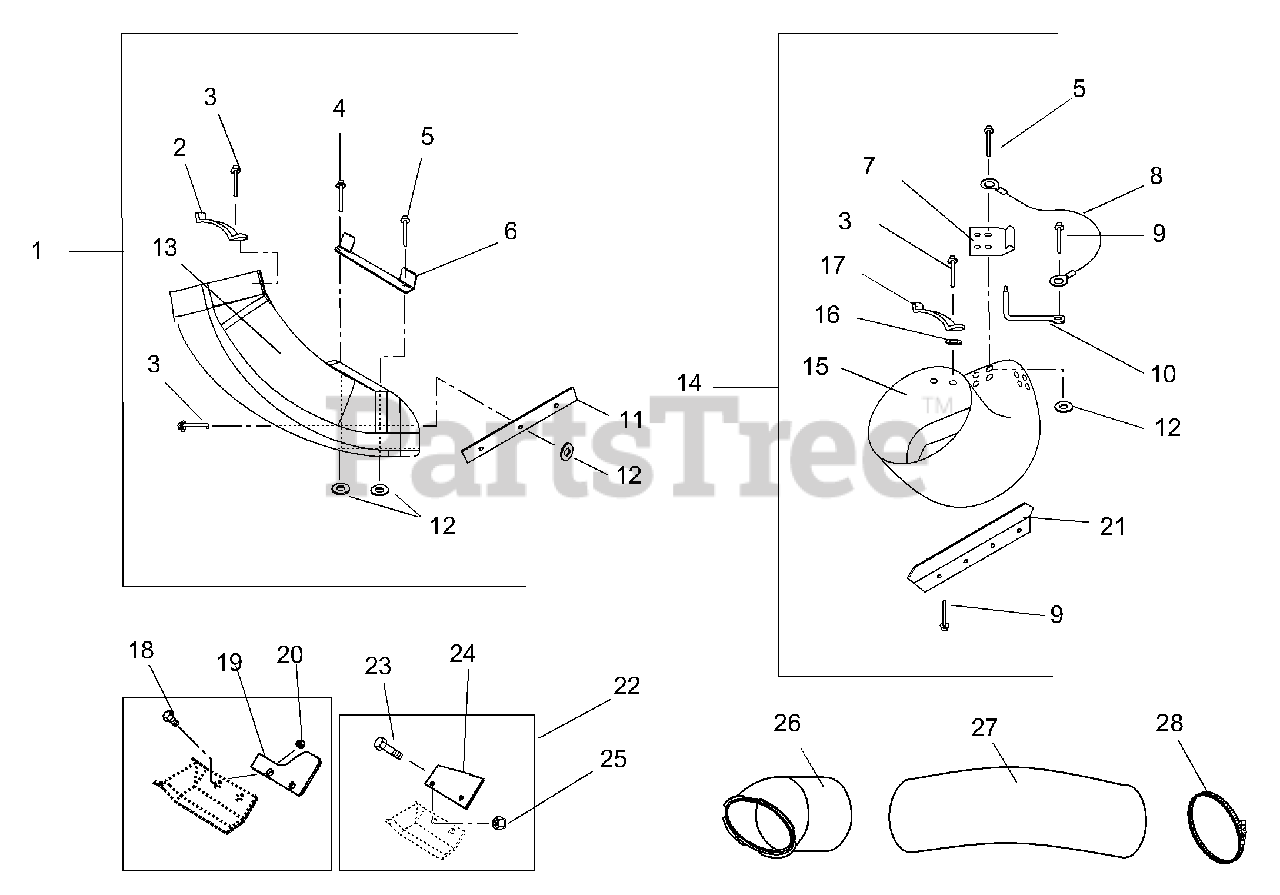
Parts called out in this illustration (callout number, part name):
1	BOOT, 28"&32" DECK BAGGER
2	TUBE RETAINER CLIP
3	RVT-POP.187X.527 DOME ST
4	RVT-POP.187X.277 DOME ST
5	RVT-POP .187X.402 DOME ST
6	BRKT, BAGGER BOOT MOUNT
7	BOOT BRACKET
8	LANYARD
9	RVT-TBLR .187X.375 ST-AL PL
10	PULL PIN
11	SKIRT, RUBBER
12	@WSHR-FL-STL.219X.50X.049 YWZC
13	28"/32" BOOT ASSY
14	MOWER BOOT ASSY- 40"
15	PAN BOOT ASSEMBLY
16	@WSHR-FL-STL.219X.50X.049 YWZC
17	TUBE RETAINER CLIP
18	BLT-HEX .31-24X.75 GR8 YWZC
20	NUT-CTRLK .31-24 YWZC
21	EXTENSION-CHUTE
22	SERVICE VANE PACKAGE
23	BLT-HEX .31-24X.75 GR8 YWZC
24	VANE
25	NUT-CTRLK .31-24 YWZC
26	BAGGER BOOT - UPPER
27	HOSE 7X38
28	CLAMP, 7" TOOL-LESS HOSE
